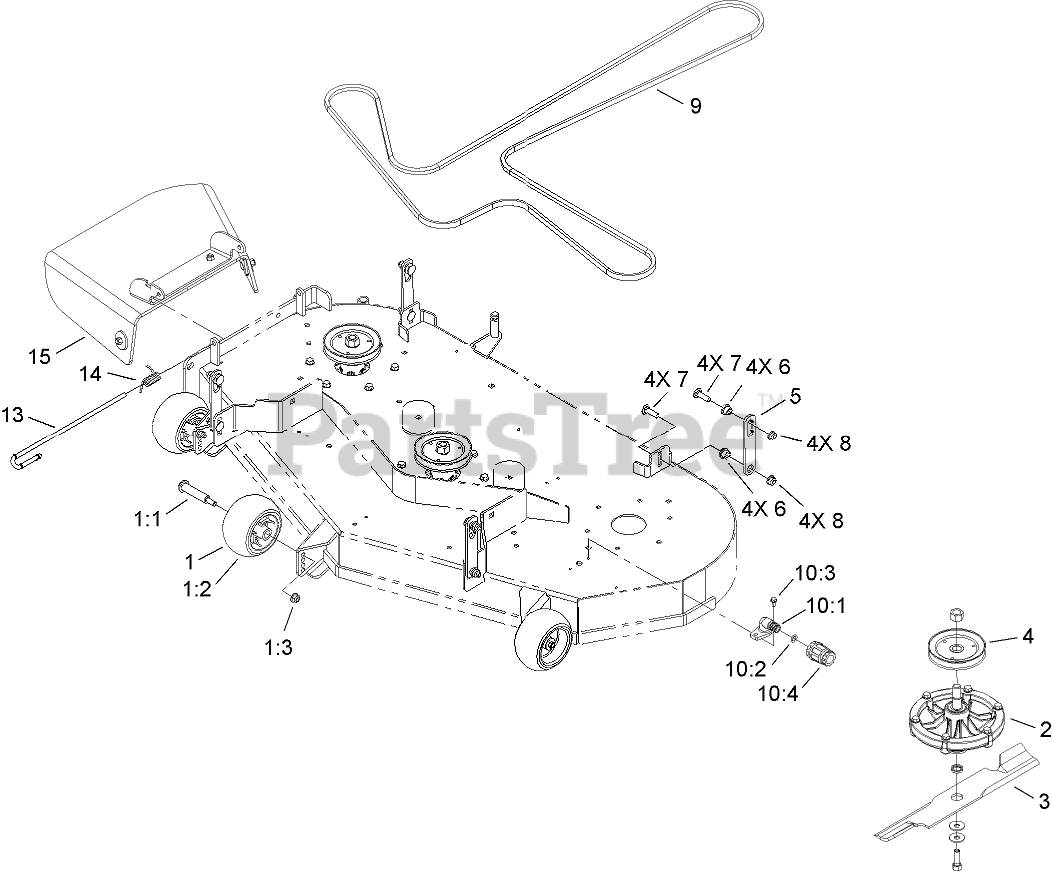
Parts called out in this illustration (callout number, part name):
1	ANTI-SCALP ROLLER KIT
1:1	BOLT-SHOULDER
1:2	ROLLER-SCALP, ANTI
1:3	NUT-HF, NI
2	COMPLETE CUTTER HOUSING ASM
3	BLADE-NOTCHED
4	PULLEY-DRIVE, BLADE
5	HANGER-DECK
6	SPACER-STRUT
7	BOLT-CARR
8	NUT-HF, NI
9	BELT
10:1	FITTING-WASHOUT
10:2	O-RING
10:3	SCREW-HWH
10:4	CONNECTOR-HOSE
13	PIN-CHUTE
14	SPRING
15	RUBBER DEFLECTOR ASM
